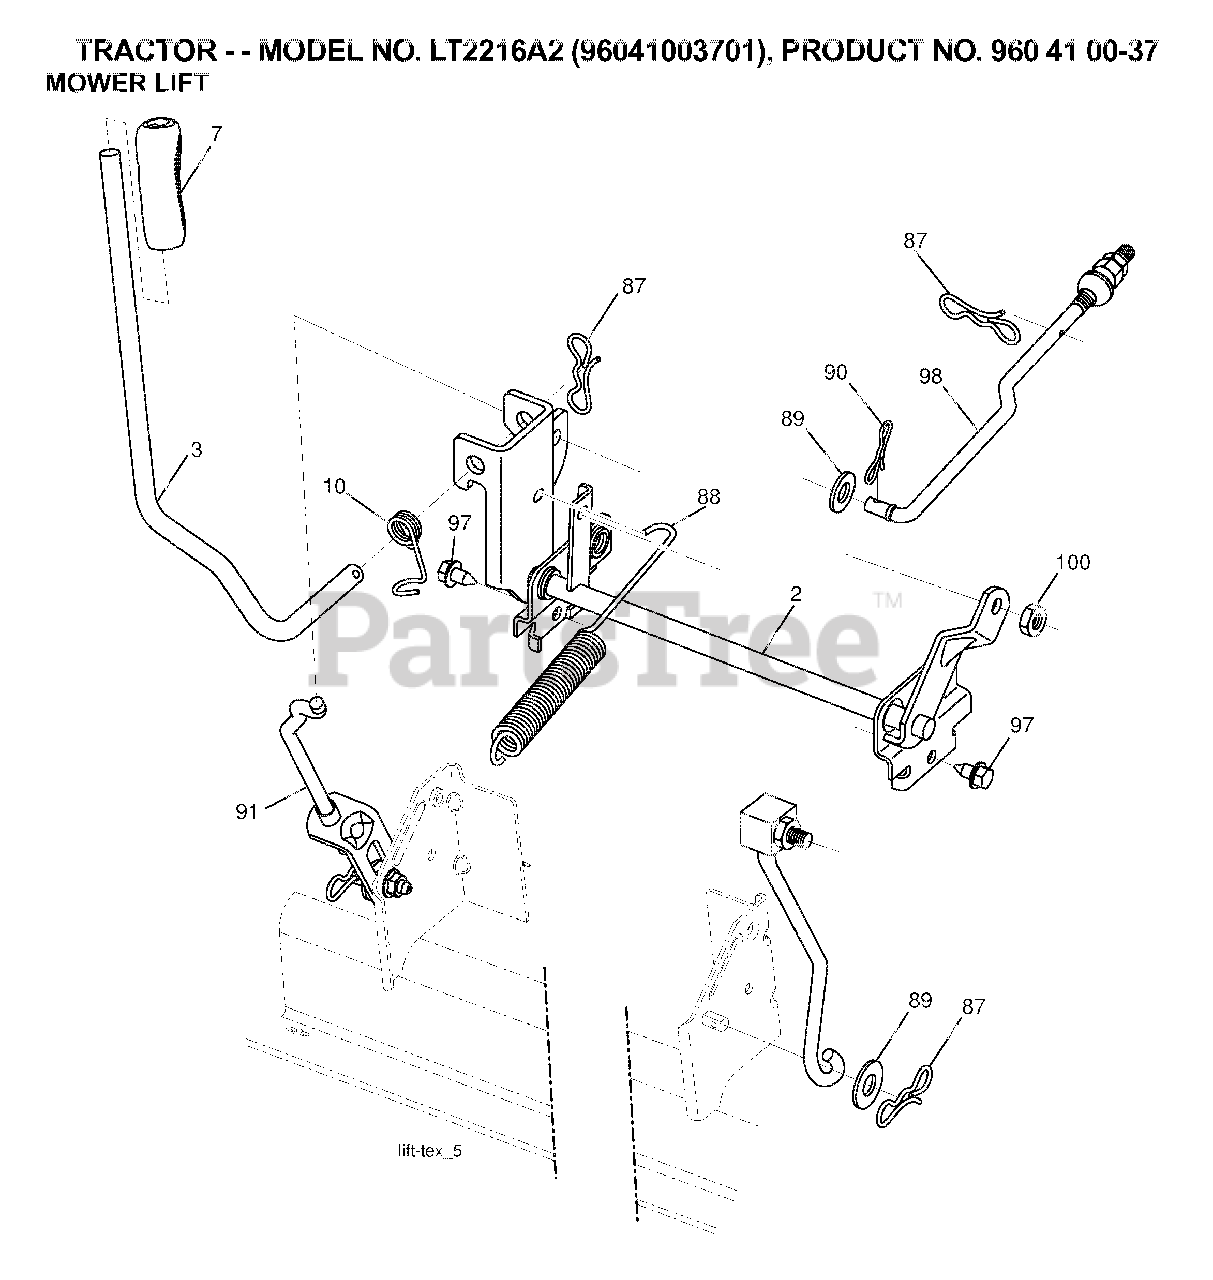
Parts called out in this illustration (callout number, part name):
2	SHAFT.ASM.LIFT.CROSS.H
3	LEVER.LIFT.HANDLE.LT
7	GRIP.HANDLE.LIFT.PVC.BLACK
10	SPRING.TORSION.LIFT.HANDLE
87	PIN.COTTER.7/16.BOW TI
88	SPRING.LIFT.ASSIST
89	WASHER.CLEAR.ZINC
90	PIN.COTTER.5/16.BOW TI
91	LINK.ASM.LIFT.REAR
97	SCREW, 3/8-16X3/4
98	LINK.ASM.SUSP.FRONT.MW
100	LOCKNUT
